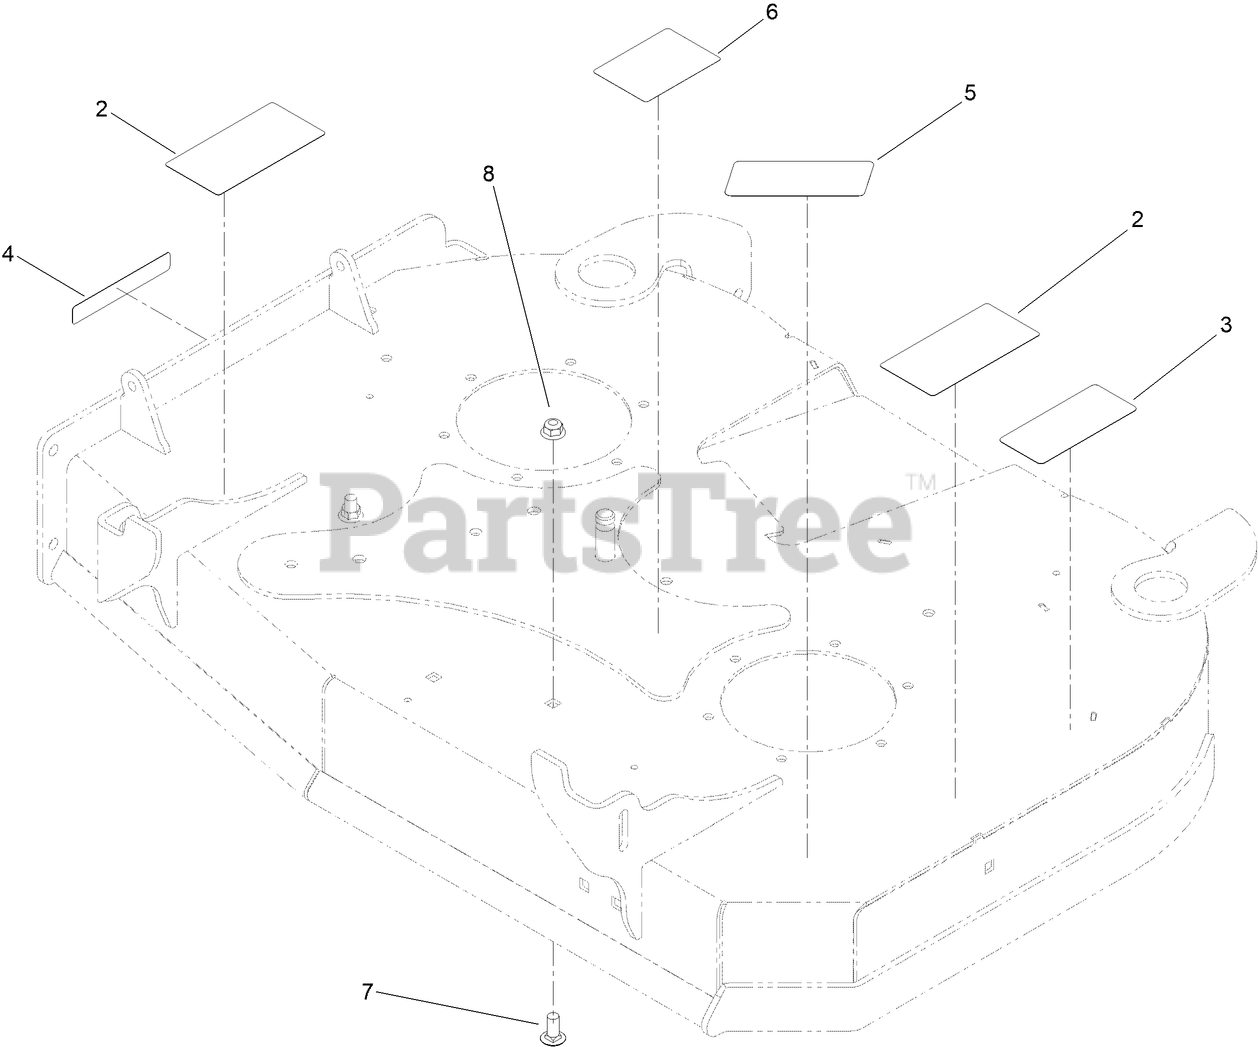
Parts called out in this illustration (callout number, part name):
2	DECAL-DANGER
3	DECAL-TORQUE, BLADE BOLT
4	DECAL-DANGER
5	DECAL-DECK, 36 INCH
6	DECAL-ROUTING, DECK BELT
7	SCREW-CARR
8	NUT-HF, NI
